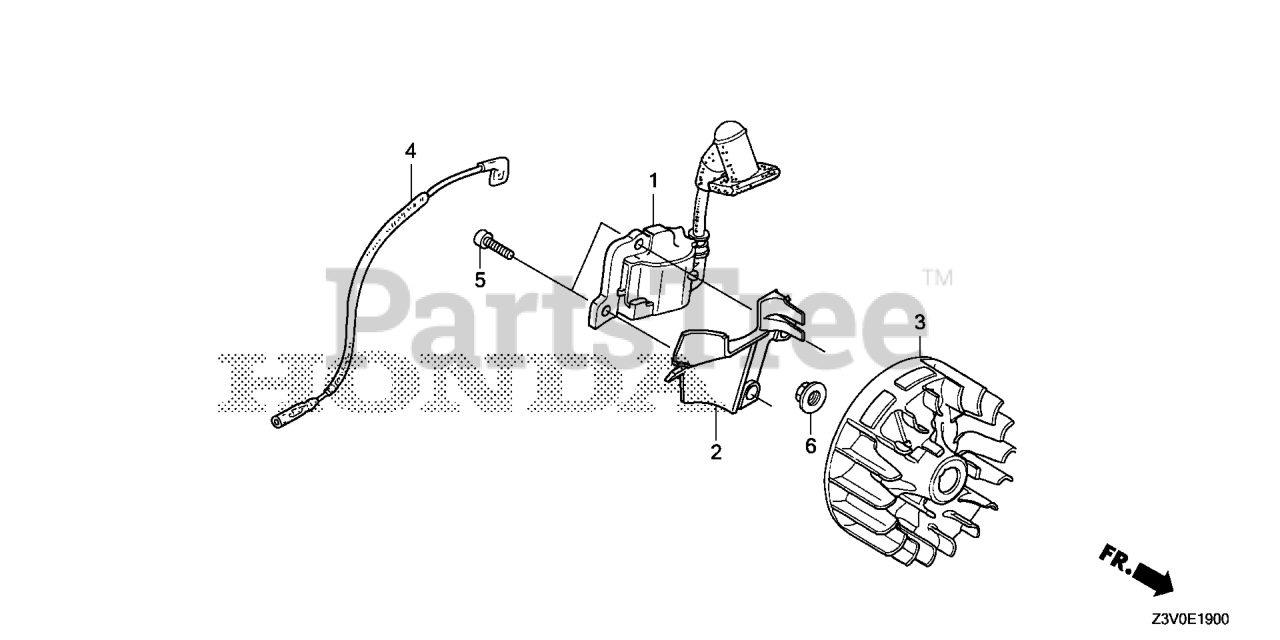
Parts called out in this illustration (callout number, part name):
1	COIL ASSY., IGN
2	CLIP, AIR GUIDE
4	WIRE, STOP SWITCH
5	BOLT, SOCKET (4X14)
6	NUT, FLANGE (8MM)
